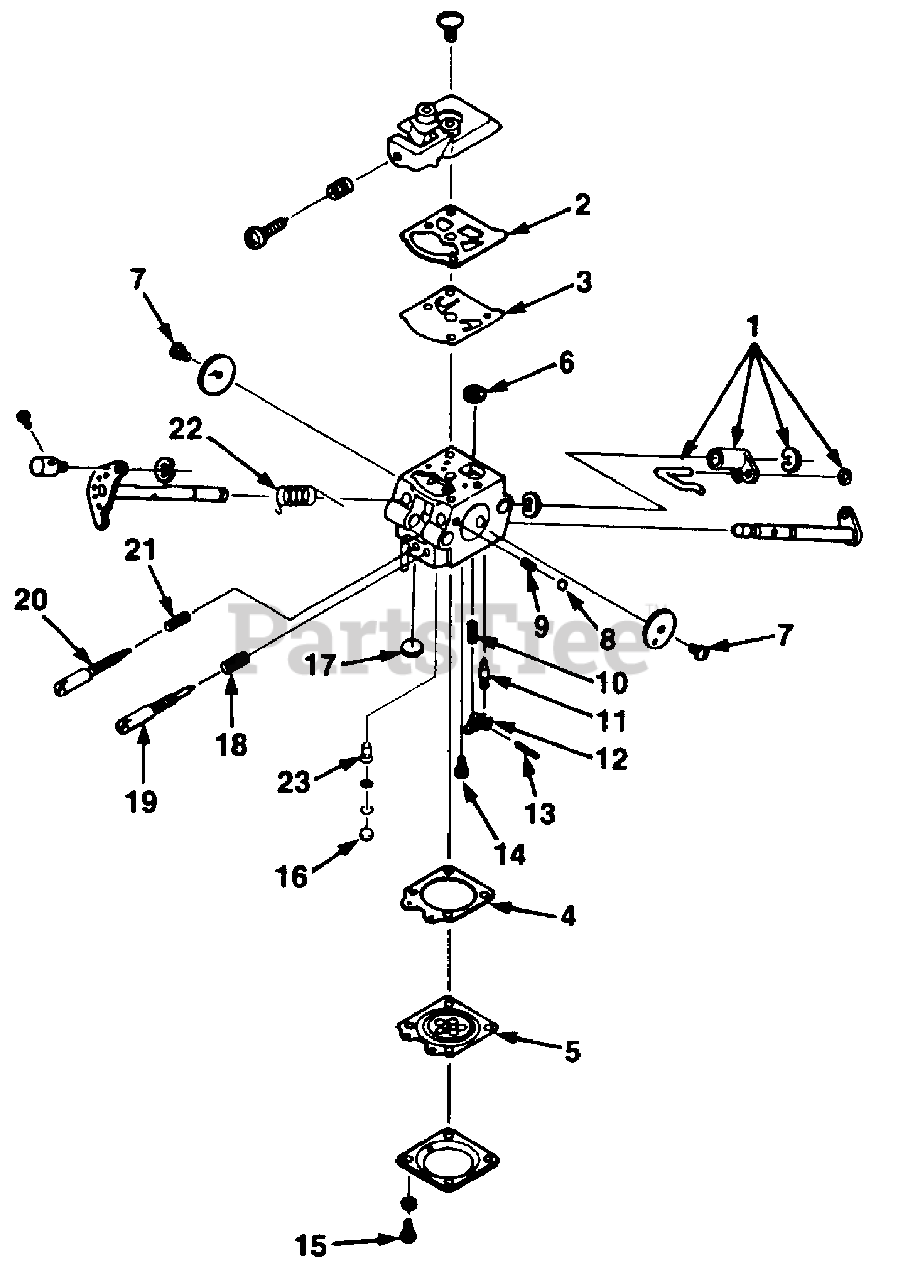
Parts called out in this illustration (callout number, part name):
1	Superseded by UP07106
2	REPAIR KIT (250)-TBO
3	REPAIR KIT (250)-TBO
4	REPAIR KIT (250)-TBO
5	REPAIR KIT (250)-TBO
6	REPAIR KIT (250)-TBO
7	REPAIR KIT (250)-TBO
8	REPAIR KIT (250)-TBO
9	REPAIR KIT (250)-TBO
10	REPAIR KIT (250)-TBO
11	REPAIR KIT (250)-TBO
12	REPAIR KIT (250)-TBO
13	REPAIR KIT (250)-TBO
14	REPAIR KIT (250)-TBO
15	REPAIR KIT (250)-TBO
16	REPAIR KIT (250)-TBO
17	REPAIR KIT (250)-TBO
18	REPAIR KIT (250)-TBO
19	REPAIR KIT (250)-TBO
20	REPAIR KIT (250)-TBO
21	REPAIR KIT (250)-TBO
22	REPAIR KIT (250)-TBO
